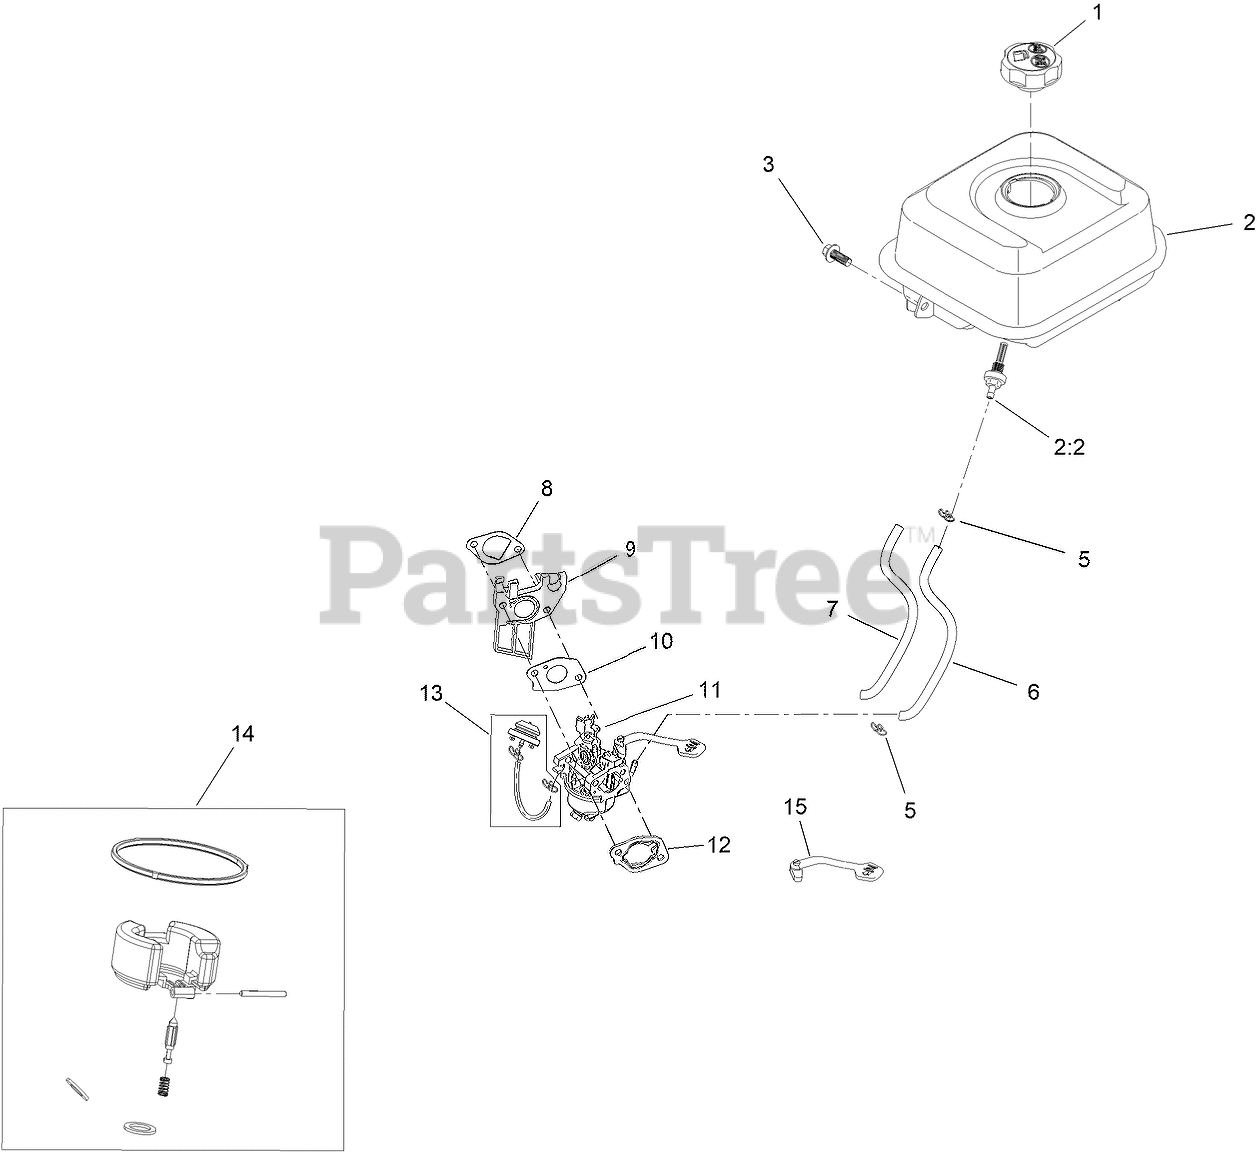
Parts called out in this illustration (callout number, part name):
1	CAP-FUEL
2	FUEL TANK AND FILTER ASM
2:2	FILTER-FUEL
3	SCREW-HHF
5	CLIP-HOSE
6	HOSE-FUEL
7	SLEEVE-ABRASION
8	GASKET-CARBURETOR
9	INSULATOR-CARBURETOR
10	GASKET-CARBURETOR
11	CARBURETOR ASM
12	GASKET-CARBURETOR
13	PRIMER KIT
14	INTERNAL CARB SERVICE KIT
15	LEVER-CHOKE
